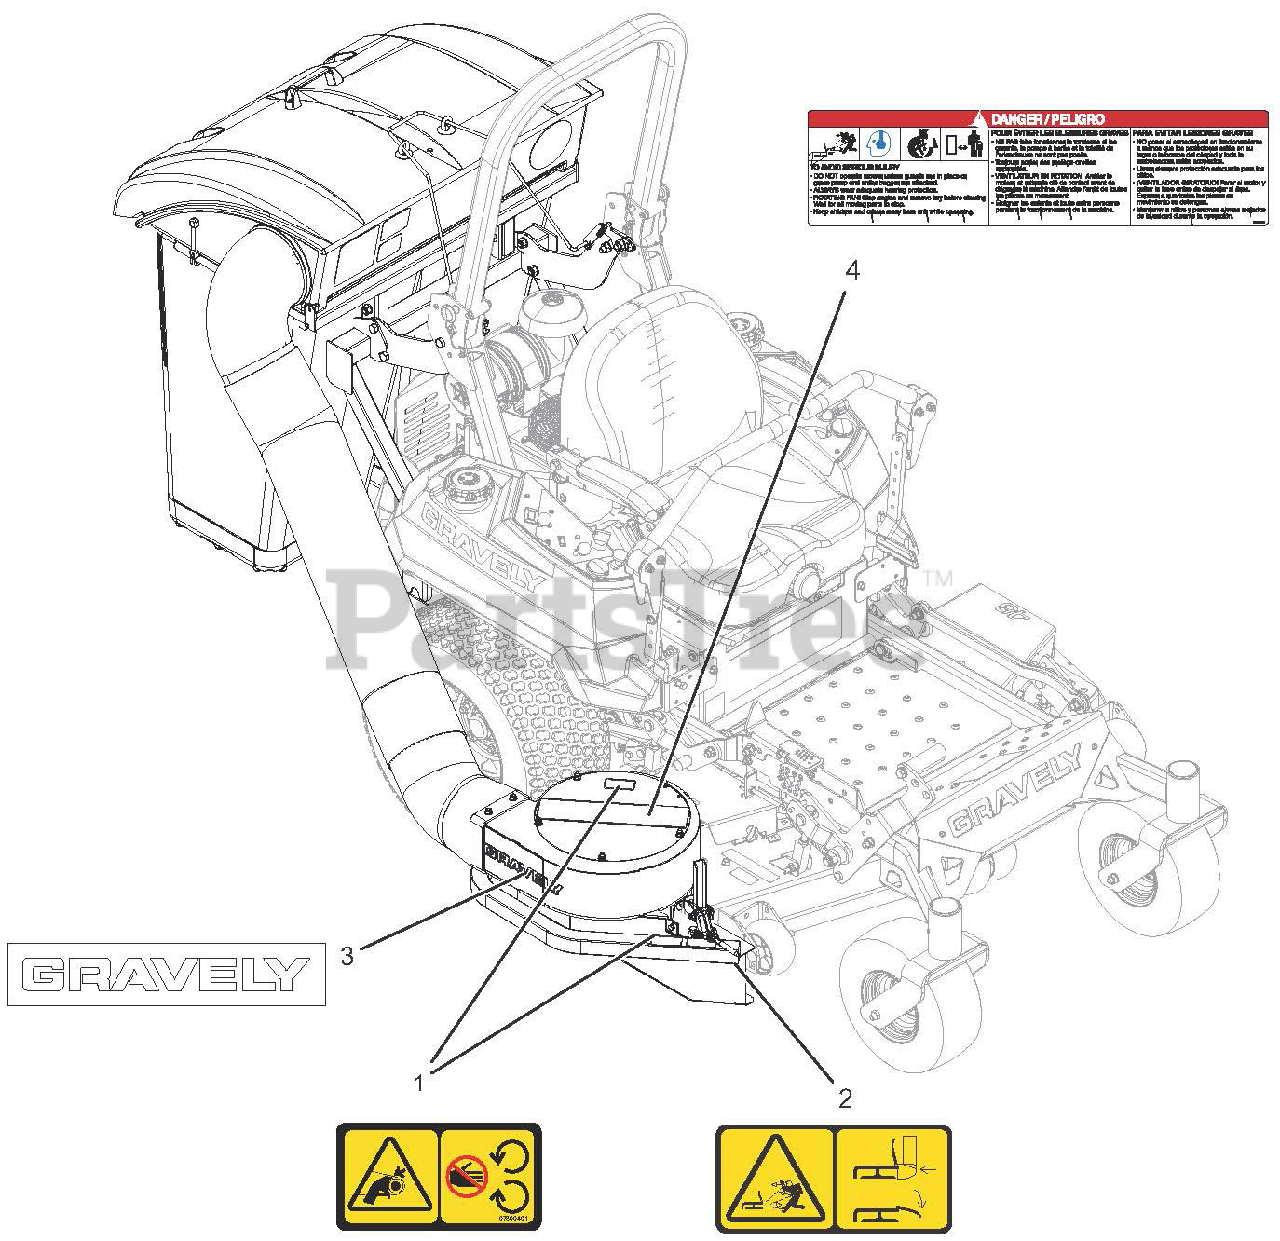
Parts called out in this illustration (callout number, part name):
1	DECAL, SAFETY - GUARDING
2	DECAL, SAFETY - DECK GUARDING
3	DECAL, 9.5" GRAVELY LOGO
4	DECAL-CAUTION, GRASS PUMP
